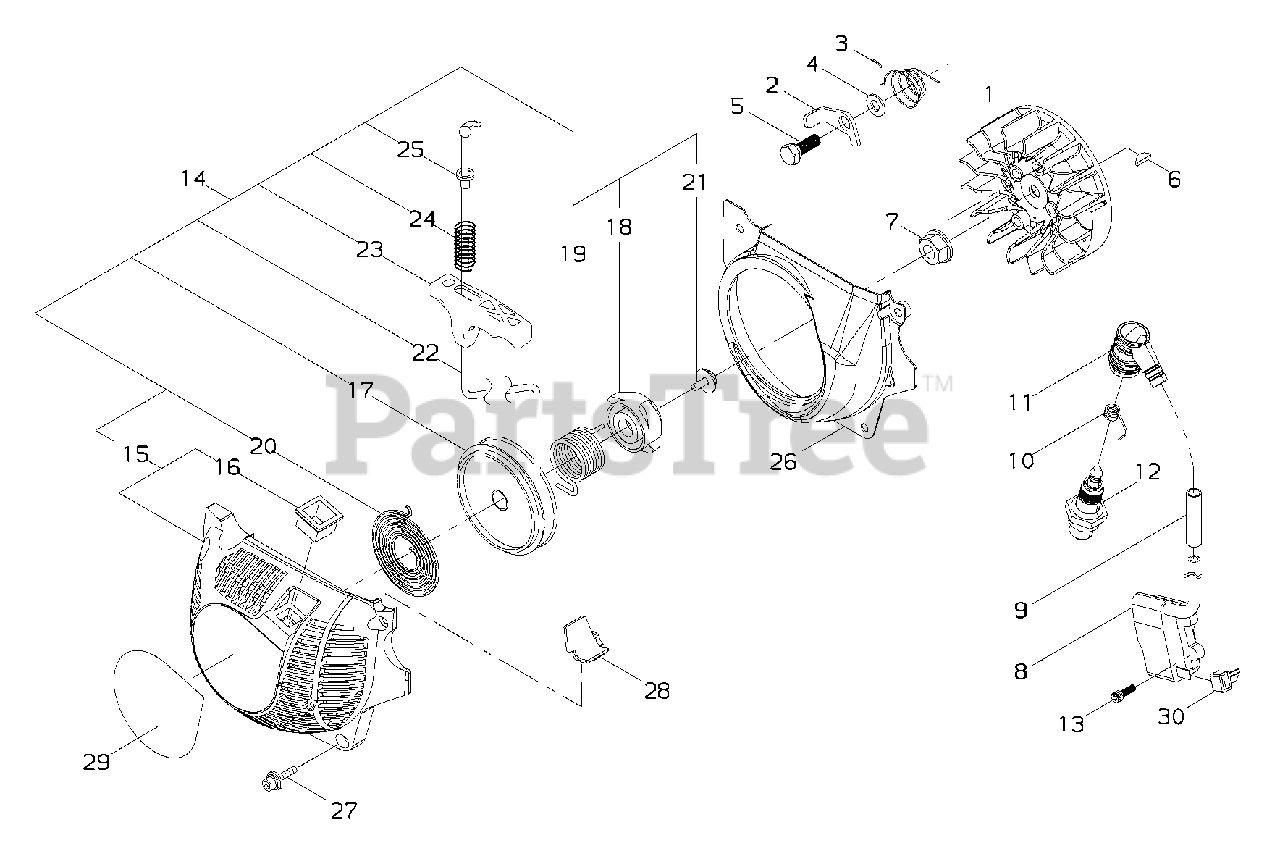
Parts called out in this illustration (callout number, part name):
1	FLYWHEEL
2	PAWL, STARTER
3	SPRING, RETURN
4	WASHER
5	BOLT
6	KEY - 3X10
7	NUT - 8
8	COIL, IGNITION
9	INSULATOR
10	TERMINAL, SPARK PLUG CAP
11	CAP, SPARK PLUG
12	SPARK PLUG -- BPMR-7A
13	SCREW - 4X20
14	STARTER ASSY
15	STARTER ASSY
16	GUIDE, ROPE
17	REEL, ROPE
18	CATCHER, PAWL
19	SPRING
20	SPRING, REWIND
21	SCREW
22	ROPE, STARTER - 3.8X750
23	GRIP, STARTER
24	SPRING
25	COLLAR
26	DEFLECTOR, AIR
27	SCREW - 4X16
29	LABEL - MODEL 446s
30	COVER, TERMINAL
